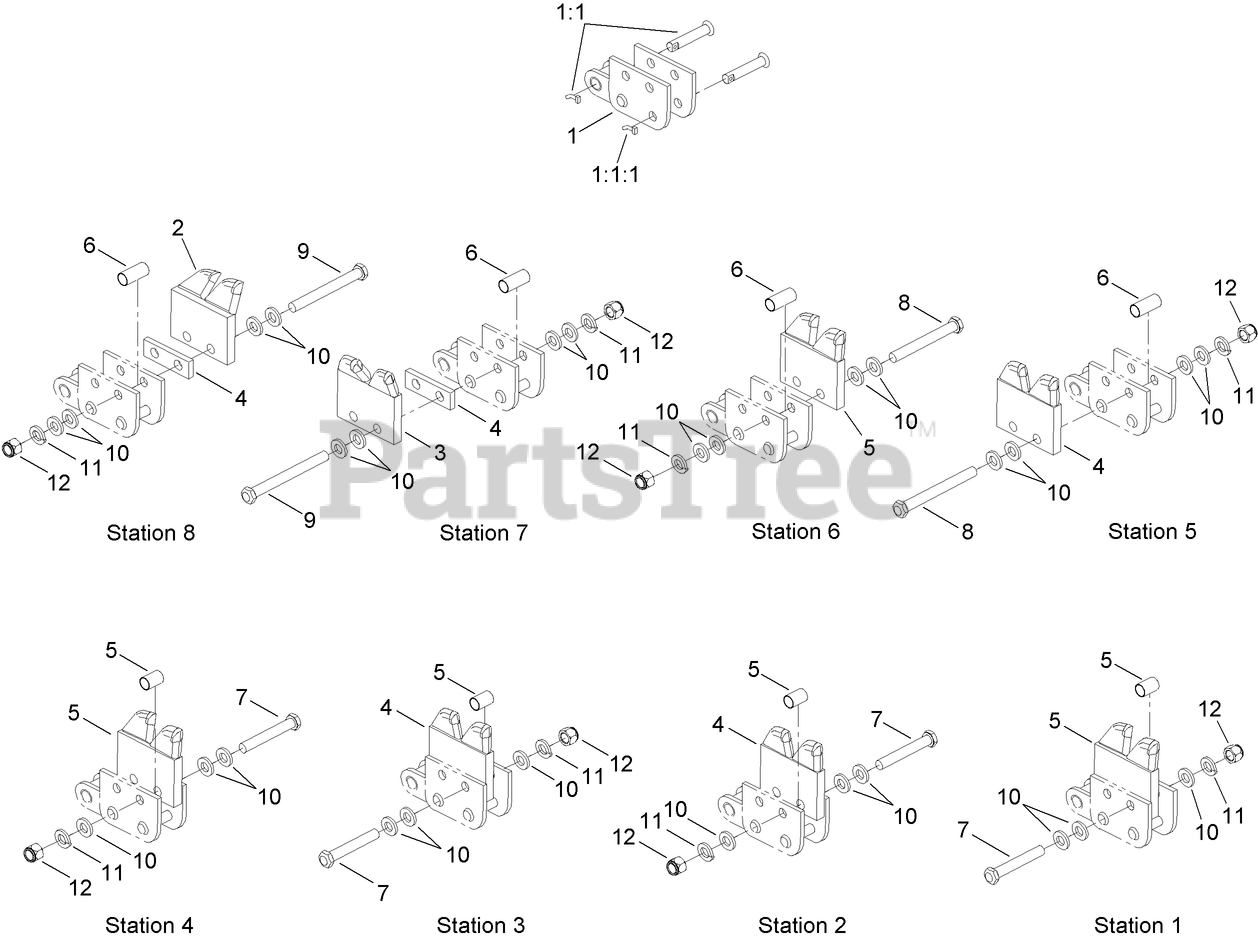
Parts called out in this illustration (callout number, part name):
1	CHAIN REPAIR LINK ASM
1:1	NOTCHED PIN AND KEEPER ASM
1:1:1	PIN-KEEPER
2	TOOTH-TERMINATOR, LH
3	TOOTH-TERMINATOR, RH
4	TOOTH-TERMINATOR, RH
5	TOOTH-TERMINATOR, LH
6	SPACER-TUBE, INSIDE ADAPTER
7	SPACER-TUBE, OUTSIDE MOUNT
8	BOLT-HH
9	BOLT-HH
10	WASHER-FLAT
11	WASHER-LOCK
12	NUT-LOCK
